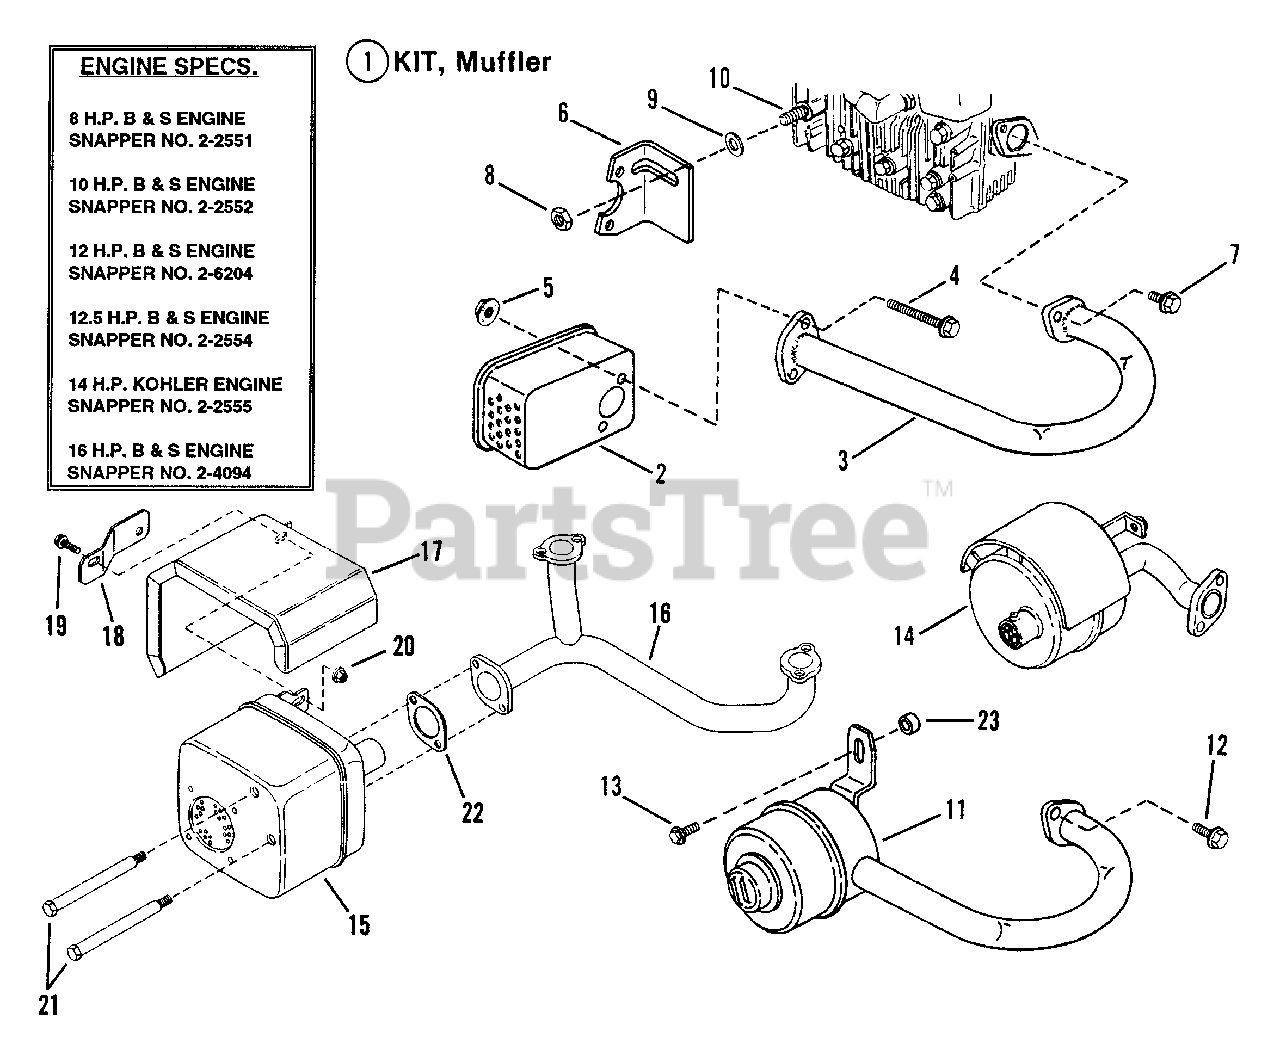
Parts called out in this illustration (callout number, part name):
1	KIT, Muffler
2	MUFFLER
3	TUBE, Exhaust
4	SCREW, 5/16-18 x 3" Hex Head Cap
5	NUT, 5/16-18 Hex Flange Lock
6	BRACKET, Muffler
7	SCREW, 1/4-20 x 5/8" Hex Head Cap
8	NUT, 5/16-18 Hex
9	WASHER, 21/64 Flat
10	STUD, Cylinder Head
11	MUFFLER
12	SCREW, 5/16-18 x 3/4" Hex Head Cap
13	SCREW, 1/4-20 x 3/4" Hex Head Cap
13	SCREW, 1/4-20 x 7/8" Machine
14	MUFFLER
15	MUFFLER
16	MANIFOLD, Exhaust
17	SHIELD, Muffler
18	BRACE, Muffler
19	BOLT, 1/4-20 x 5/8" Hex Flange Lock
20	NUT, 1/4-20 Hex Flange Lock
21	BOLT, 5/16-18 (1/2") x 4" Shoulder
22	GASKET, Exhaust
23	SPACER
